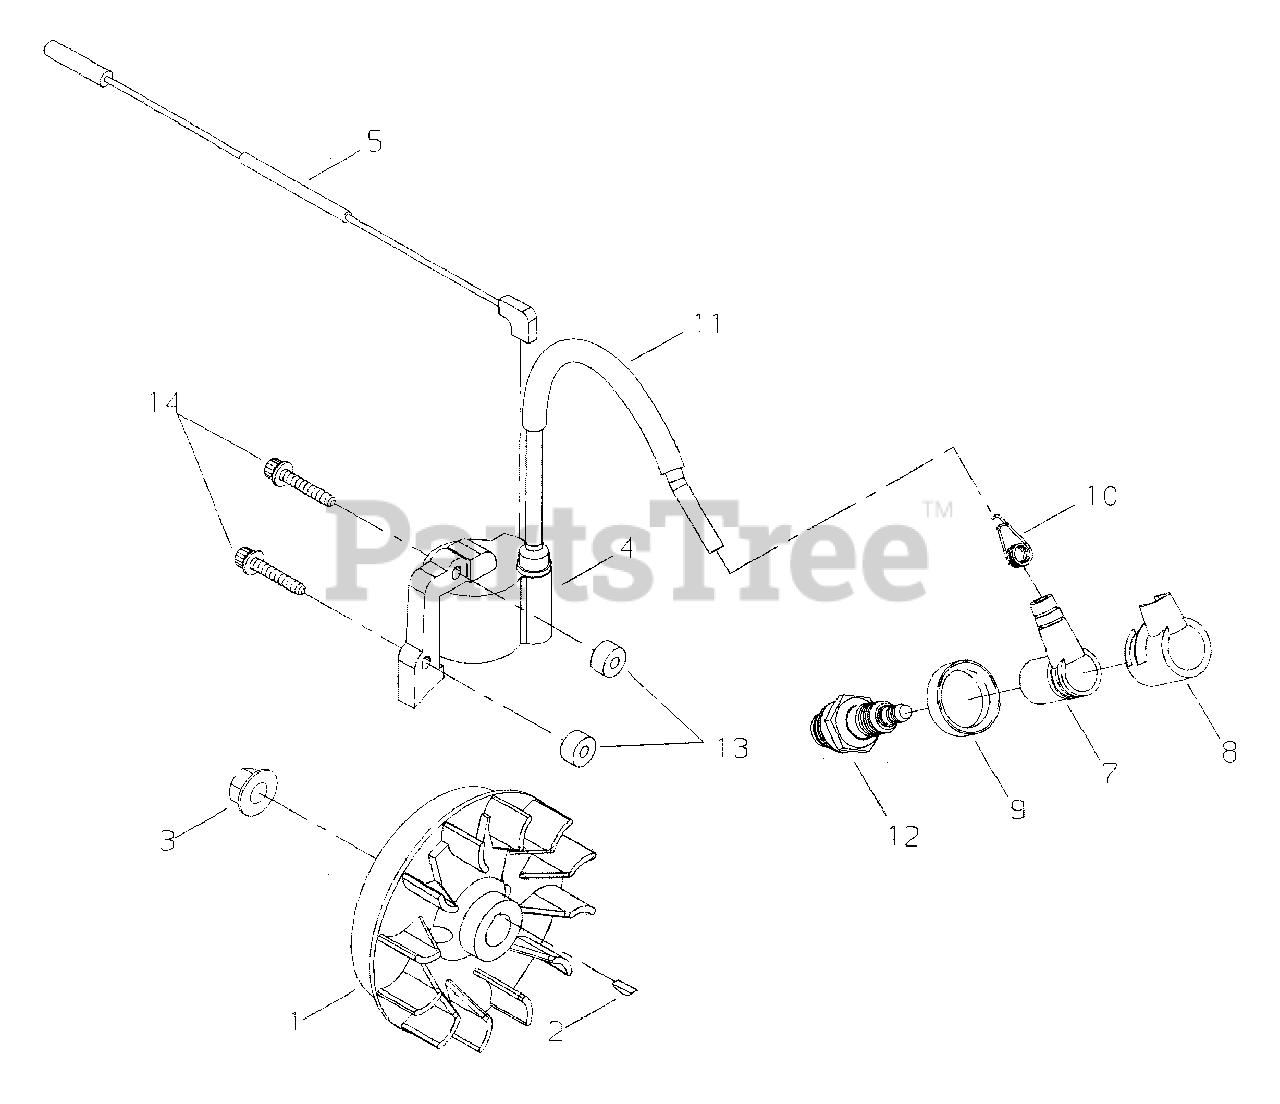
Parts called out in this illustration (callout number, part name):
1	FLYWHEEL
2	KEY, WOODRUFF 3×10
3	NUT M8
4	COIL, IGNITION
5	LEAD - IGNITION
7	CAP, SPARK PLUG
8	COVER, CAP
9	SEAL, SPARK PLUG
10	TERMINAL, SPARK PLUG
11	TUBE, IGNITION COIL
12	SPARK PLUG
13	INSULATOR 4.2×11×6
14	BOLT M4×26
